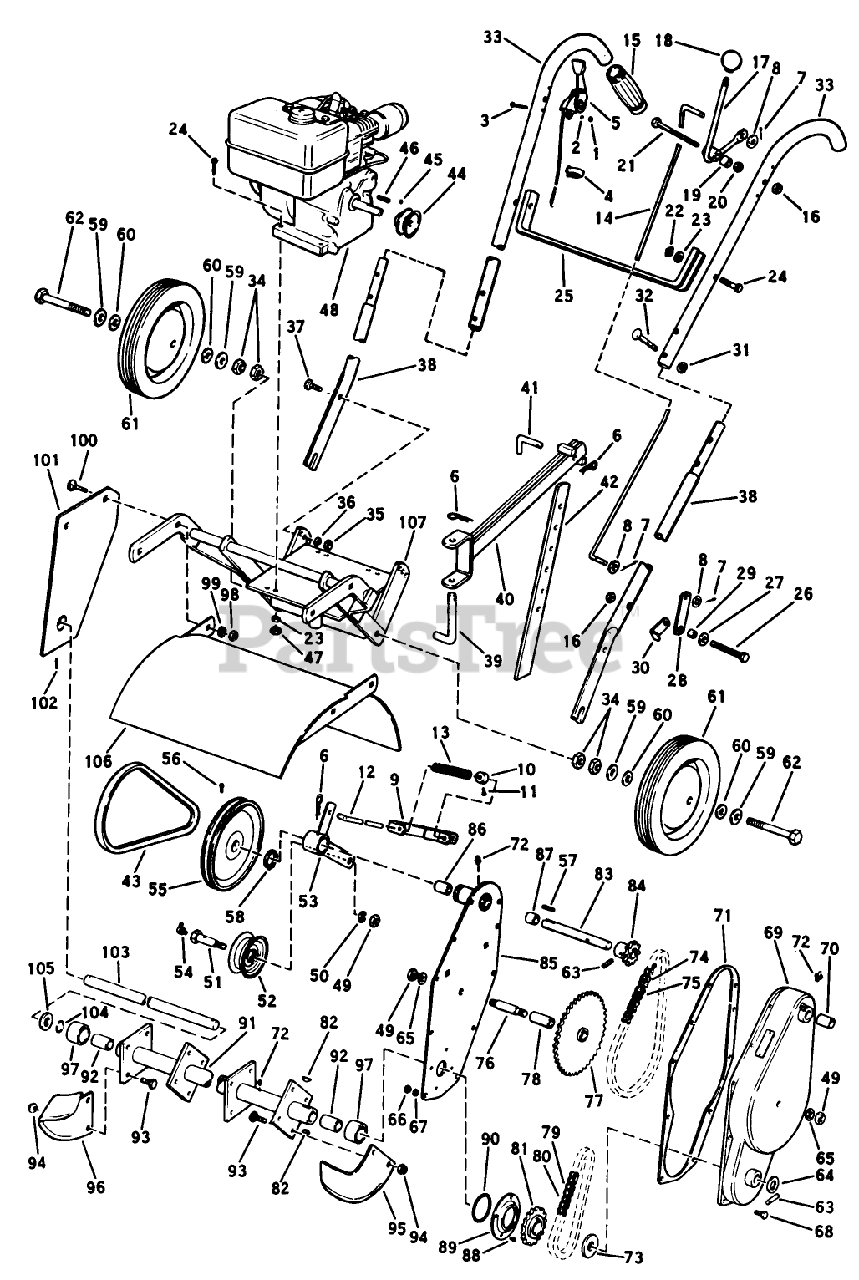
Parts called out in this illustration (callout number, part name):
1	Hex Nut #8-32
2	Lockwasher
3	Machine Screw #8-32 x 1-1/2 Lg.
4	Cable Clip
5	Throttle Control Assembly
9	Spring Bracket Assembly
10	Set Collar
11	Set Screw
12	Engine 8 H.P.
13	SRV BULLT 437B
16	Locknut 3/8-24
17	Control Lever Assembly
20	Jam Nut 3/8-24
22	Square Nut 5/16-18
24	Capscrew 5/16-18 NC x 1-1/2 Lg.
26	Capscrew 3/8-24 x 1-3/4 Lg.
28	Shifting Lever
31	Locknut 5/16-18
32	Capscrew 5/16-18 x 1-1/4 Lg.
34	EXTENSION BOOM PIPE ASSY
35	BOOM SWITCH
37	Capscrew 3/8-16 NC x 1-1/4 Lg.
38	Handle Bar Tube Assembly
40	Beam Assembly
41	Selector Pin
42	Depth Bar
43	V Belt 37" A Section
45	Set Screw 5/16-18 NC x 5/16 Lg.
46	Key 3/16 Sq. x 1-1/8
49	Jam Nut 1/2-20
50	Lockwasher
52	Idler Pulley
53	Idler Arm Assembly
54	Grease Fitting 1/4-28-90?
56	Set Screw 5/16-18
58	Snap Ring
59	Washer 1/2 SAE
61	Wheel Assembly 10 x 1.75
63	Roll Pin 3/16 x 1-1/8
65	Lockwasher, Shakeproof
66	Hex Nut 1/4-20
67	Lockwasher, Shakeproof
68	Capscrew 1/4-20 x 5/8 Lg.
69	Cover Assembly
70	Bushing
72	Grease Fitting 1/4-28 St.
73	Thrust Washer
74	Chain #41-1/2 Pitch, 55 Links
76	Intermediate Shaft
77	Sprocket Cluster Assy
78	Bushing
79	Extension-Chute
82	Woodruff Key
84	Input Sprocket and Hub Assv.
85	Back Plate Assembly
86	Bushing
87	Bushing
89	Oil Seal Retainer
90	Ring (Neoprene)
91	Rotor Tube Assembly
92	Bushing
94	Marsden Nut 3/8-24
96	Tine LH
98	Hex Nut 3/8-16
99	Lockwasher
100	Carriage Bolt 3/8-16 x 1 Lg.
101	Side Plate Assembly
102	Roll Pin
103	Rotor Shaft
105	Thrust Washer
106	Hood Assembly
